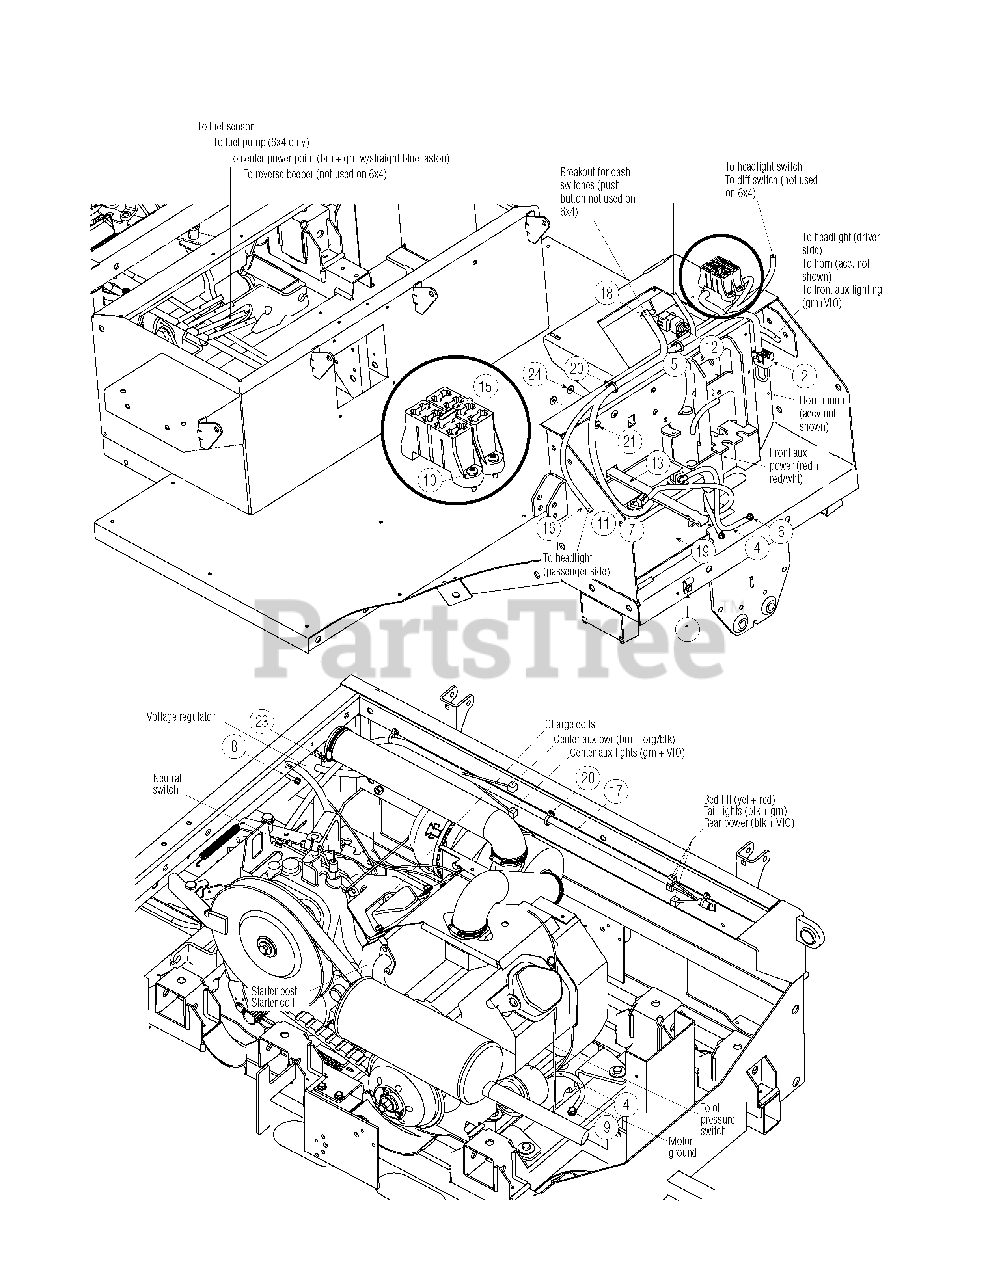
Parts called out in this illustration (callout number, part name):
1	Bracket, Retainer Hook
2	Connection Assembly
3	Harness Assembly, Utility Starter
4	Harness Assembly, Ground
5	Screw, Self-tapping 1/4-20
6	Screw, Self-tapping, 1/4-20 x 0.500
7	Screw, Hex Carriage, 1/4-20 x .75
8	Screw, Self-tapping, 1/4-20 x 1.000
9	Screw, 5/16-18 x.75
10	Screw, #10-24 x 0.75
11	Nut, Hex Sems, 1/4-20
12	Cover, Protection
13	Strap, Battery
15	Fuse, 5 Amp
16	Harness, Utility Wire, Main
17	Harness, Kohler Motor Wire
18	Switch, Interlock
19	Battery, 300 CCA
20	Cable Tie, 19" x 8.39"
21	Rivet, Pop
23	Lock Washer, 1/4
24	Washer, Flat .194 x .62 x .063
